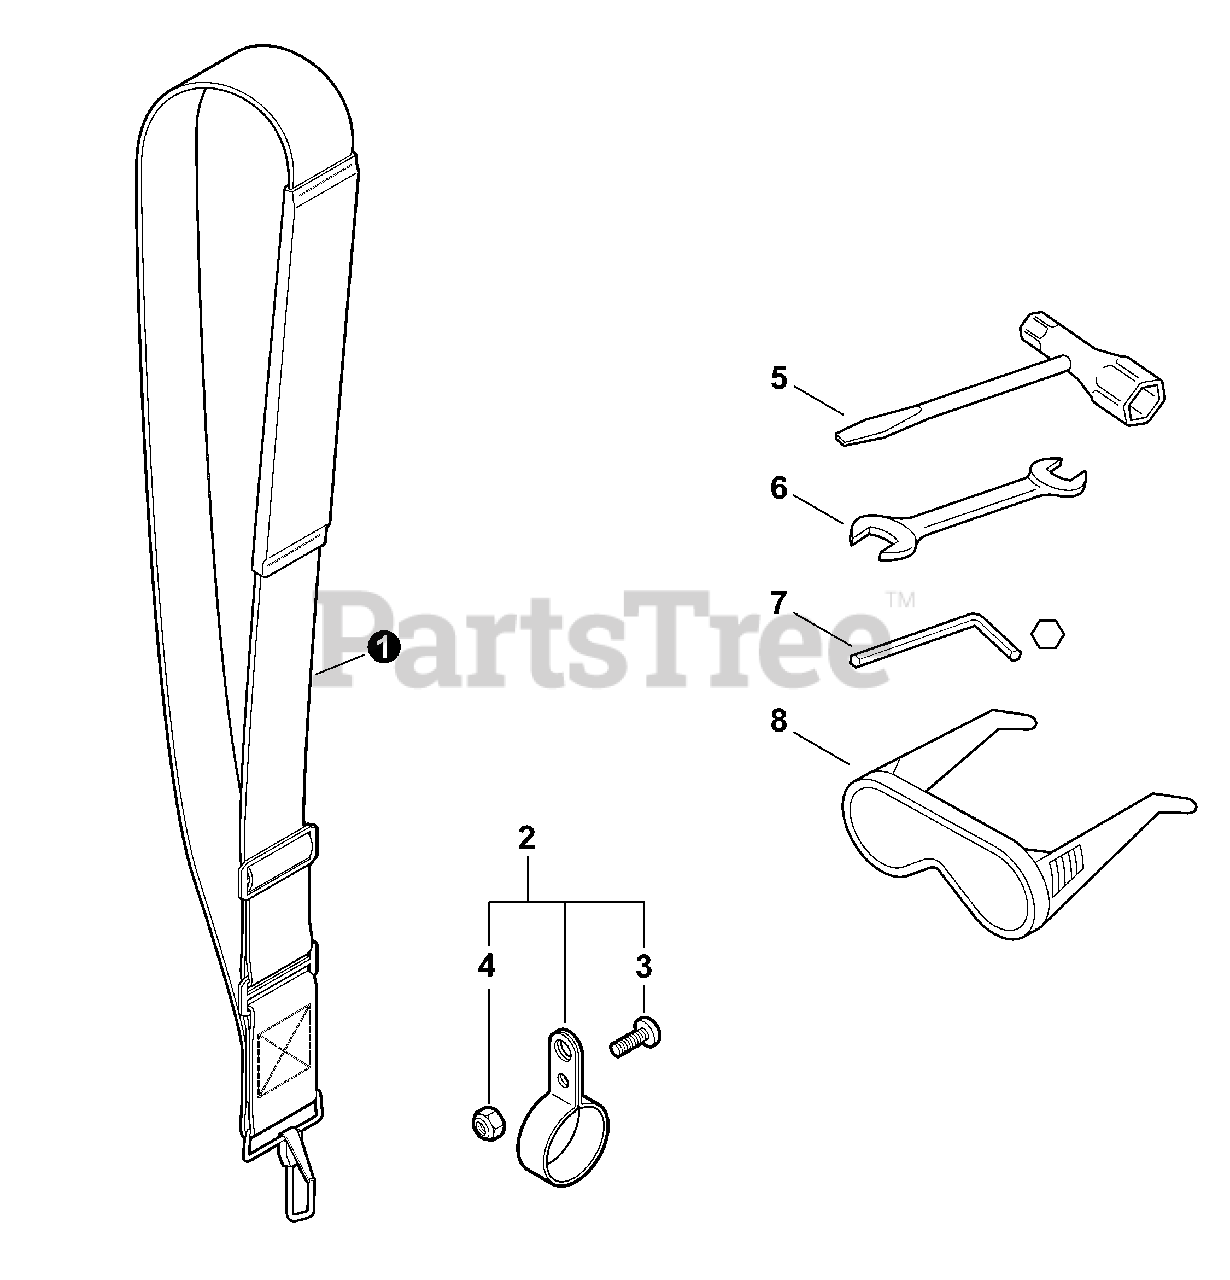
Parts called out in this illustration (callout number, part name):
1	SHOULDER STRAP ASY
2	HANGER KIT
3	SCREW - TORX PAN HEAD
5	T-WRENCH - 10×19mm
6	SPANNER - 8×10mm
7	KEY - HEX -- 4mm
8	GOGGLES
